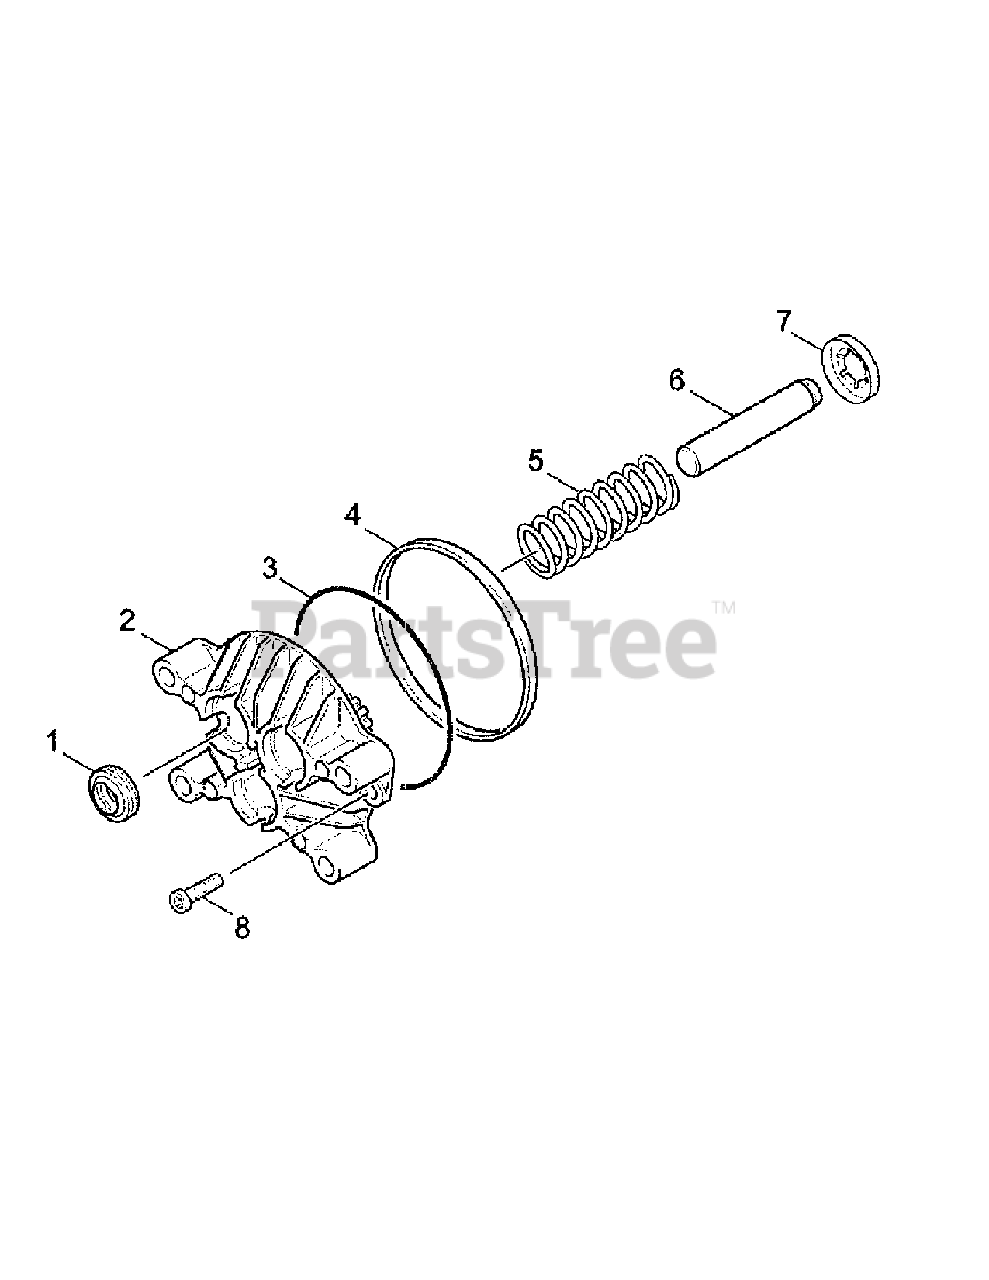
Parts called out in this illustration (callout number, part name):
1	Grooved Ring
2	Housing
3	Gasket
4	Ring
5	Spring
6	Piston
7	Retainer
8	Screw
